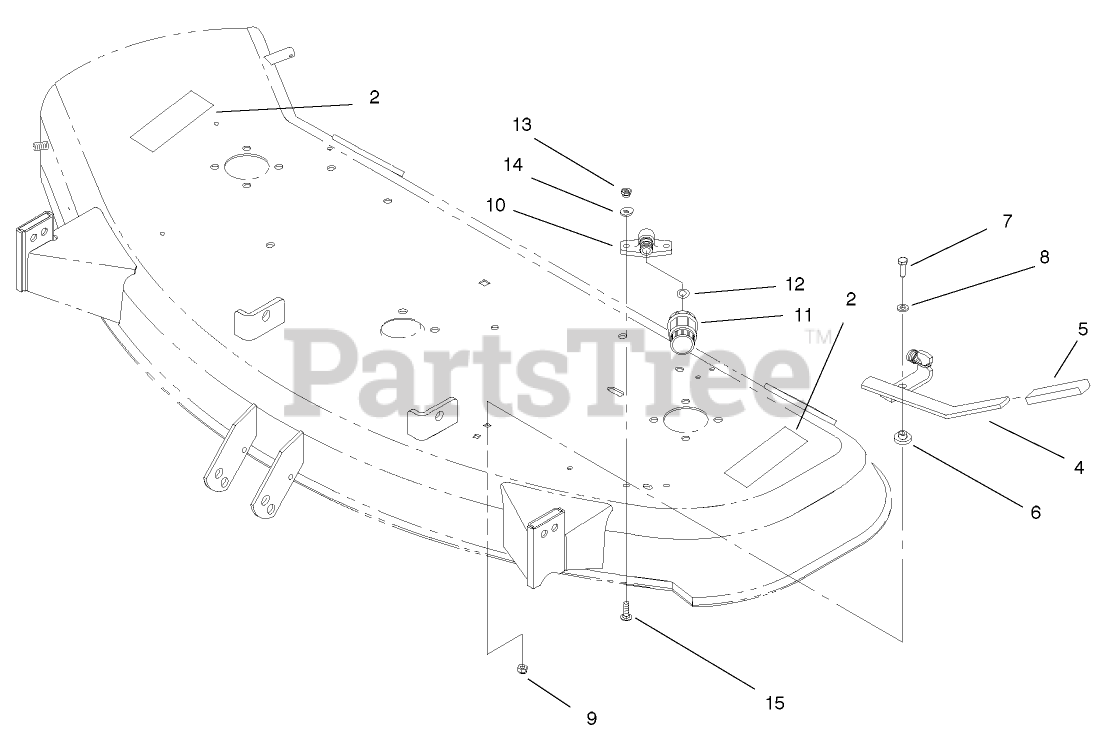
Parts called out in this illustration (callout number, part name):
2	DECAL-DANGER
4	LEVER ASM
6	SPACER-RACK, STEERING
7	SCREW-HH
8	WASHER-PLAIN
9	NUT-LOCK, NI
11	CONNECTOR-HOSE
12	O-RING
13	NUT-LOCK, NI
14	WASHER-FLAT
15	BOLT-CARR
